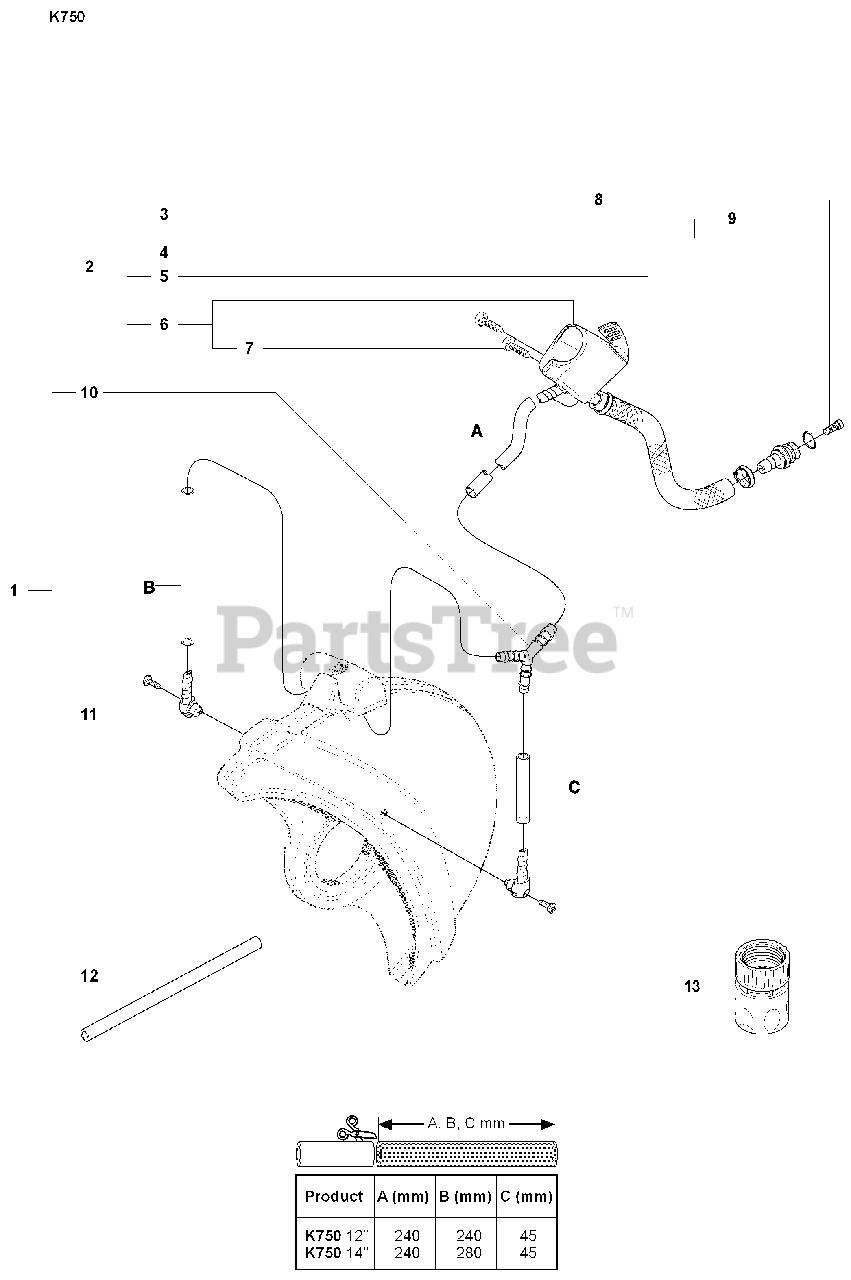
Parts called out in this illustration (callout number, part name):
1	WATER HOSE KIT
2	HOSE
3	NIPPLE
4	HOSE CLAMP
5	HOSE
6	VALVE ASSY
8	FILTER
9	O-RING
12	HOSE
13	COUPLER
